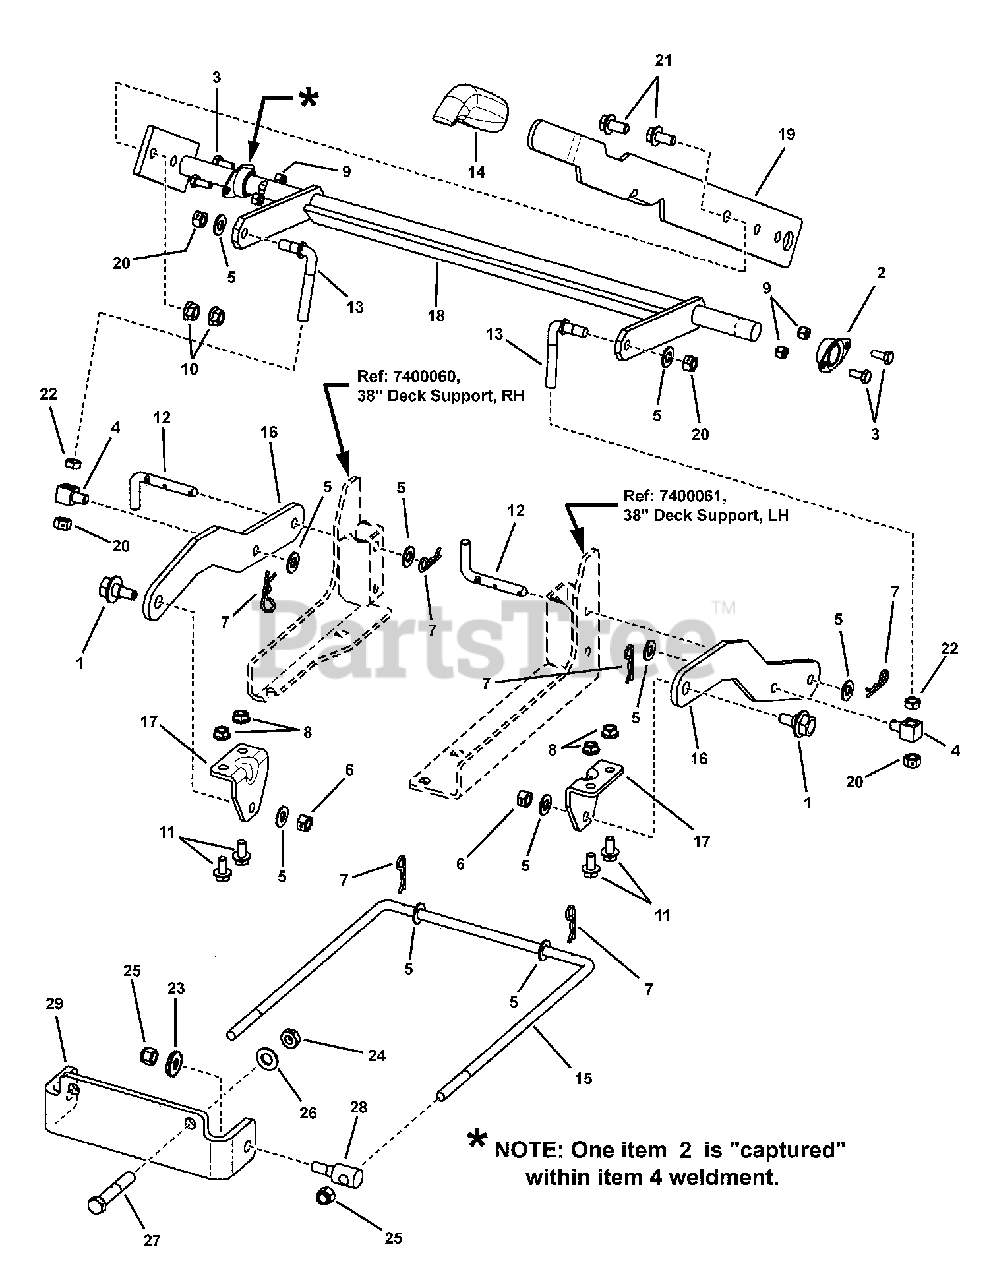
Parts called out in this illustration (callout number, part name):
1	HFB, 3/8F GR8
2	BEARING, Flange, .75 ID Powdered Metal
3	CAPSCREW, Hex Head, 1/4C X5/8 GR5 YZ
4	SWIVEL, In-Line Brake Arm, Yellow
5	WASHER, 3/8 SAE YZ
6	NUT, Hex Center Lock, 3/8F GR5 YZ
7	HAIR PIN, 3/32X1-1/2
8	NUT, Hex Flange Lock, 5/16C GR5 YZ
9	NUT, Hex Lock Nylon, 1/4C YZ
10	NUT, Hex Flange Lock, 3/8C YZ
11	CAPSCREW, Hex Head, Whiz Lock, Flange, 5/16C X5/8 GR5 YZ
12	PIN, Quick Hitch
13	LINK, Leveling, RZT
15	ROD, Deck Hanger FrontT, 38/42
16	BAR, Rear Lift, 38/42
17	BRACKET, Deck Hanger
18	WELD, Deck Lift, 38/42
19	HANDLE, Deck Lift
20	NUT, Hex Center Lock, 3/8C GR5 YZ
21	CAPSCREW, Hex Head, Whiz Lock, Flange, 3/8C X3/4 GR5 YZ
22	NUT, Hex, Jam, 3/8C YZ
23	WASHER, .406X1.25X.132 ZP
24	NUT, Hex Center Lock Jam, 7/16F GR5 YZ
25	NUT, Hex, 3/8C, Nylock YZ
26	WASHER, .47X.92X.065 YZ
27	CAPSCREW, Hex Head, 7/16F X2-1/2 GR5 YZ
28	SWIVEL, 3/8, Yellow
29	BRACKET, Quick Hitch
